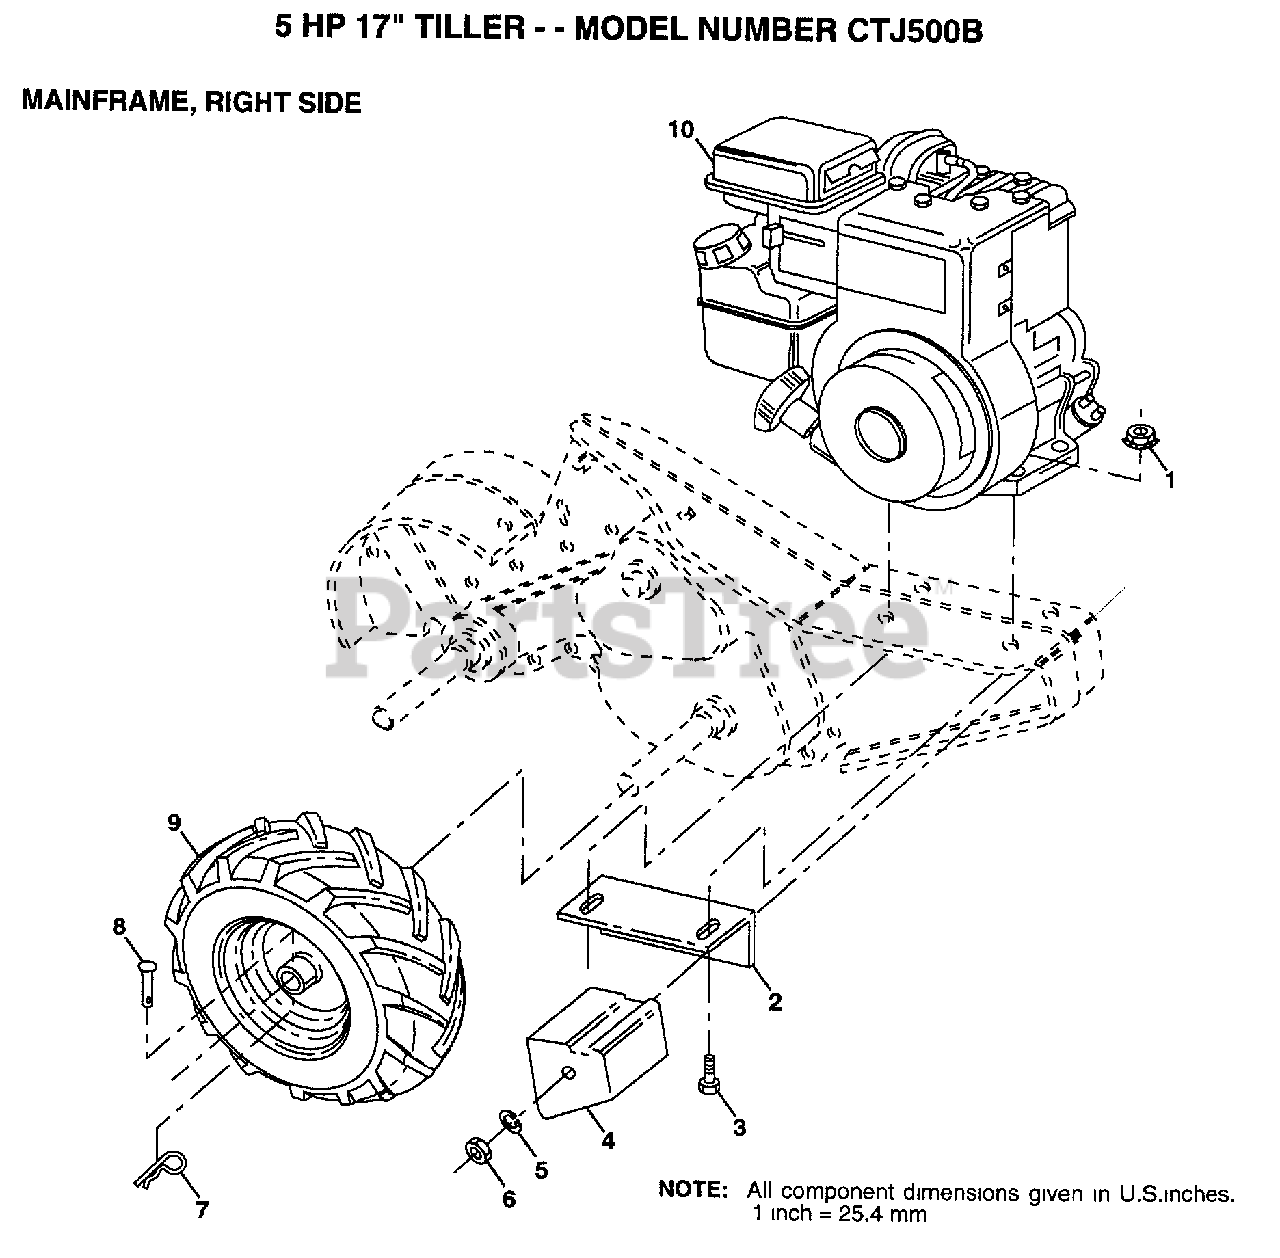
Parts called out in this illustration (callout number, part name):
2	BRACKET RH CRT
3	BOLT.HEX.5/16-1.5
4	COUNTERWEIGHT CRT
5	LOCKWASHER
6	NUT.HEX.3/8-16UNC
7	RETAINER M
8	RIVET.DRILL.1.75
9	TIRE.CHV.13X5.0-6
